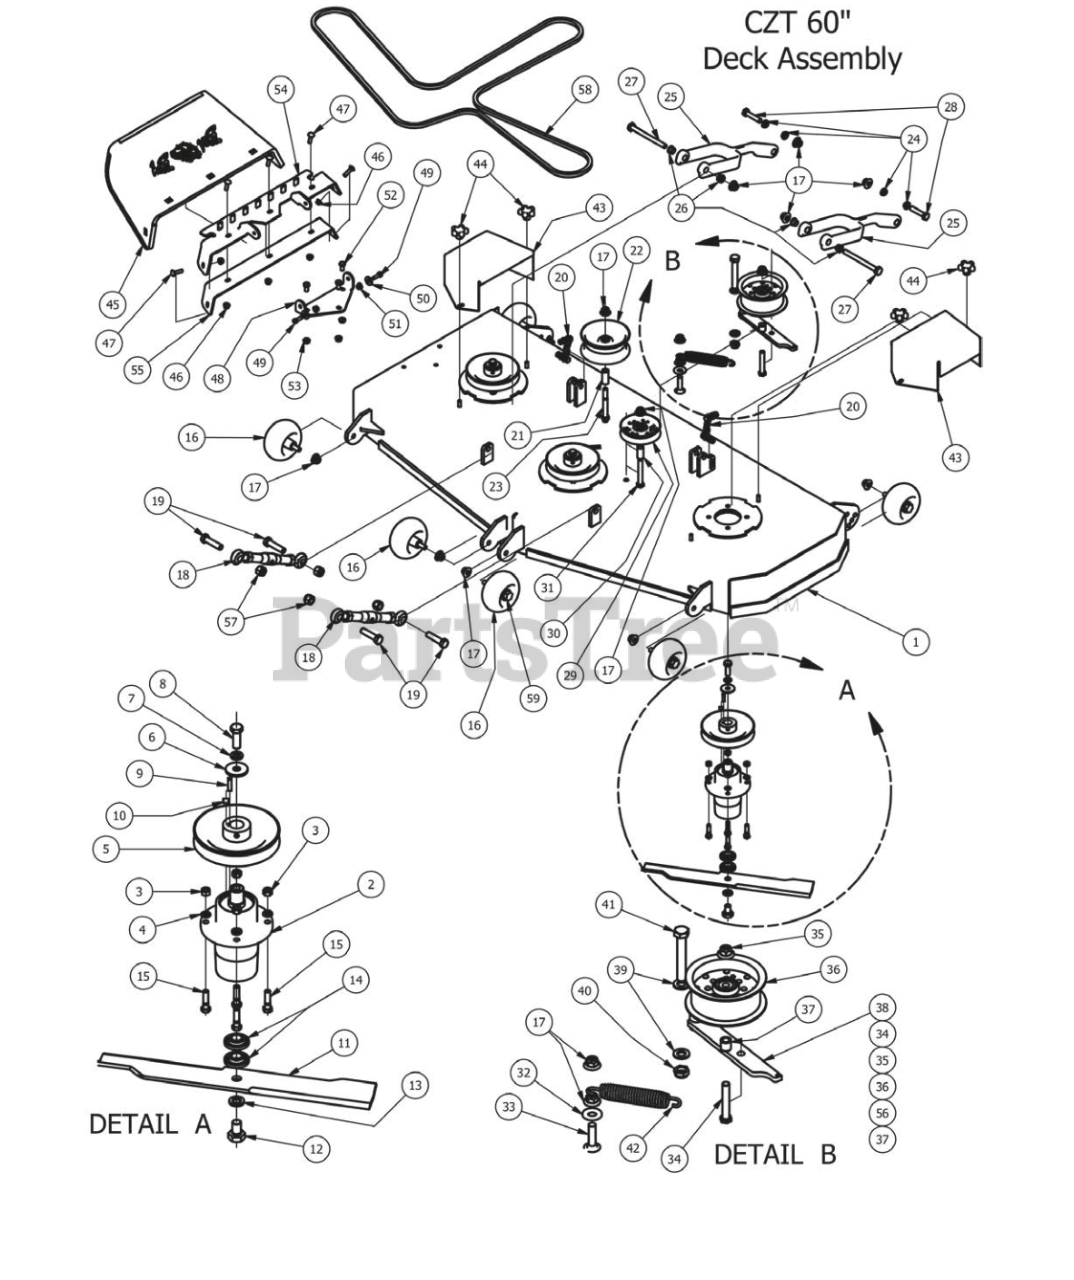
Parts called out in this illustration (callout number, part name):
1	2013 60" CZT Deck
2	Short Shaft Spindle
3	3/8" Hex Nut
4	3/8" Lock Washer
5	6 1/4" Drive Pulley
6	1/2 Belleville Washer
7	1/2" Lock Washer
8	1/2"-20 x 1 1/2 - Grade 5 Fine Thread Bolt
9	1/4" x 1" Key
10	5/16 Set Screw
11	60 Inch Fusion Blade
12	5/8" x 1 1/2" Grade 8 Bolt
13	5/8" Lock Washer
14	Spindle Bearing
15	3/8" x 1 1/2" Hex Bolt
16	Deck Wheel
17	1/2-13 Nylon Flange Nut-Orange
18	Turnbuckle (Top Link)
19	5/8" x 2 1/2" Hex Bolt
20	Chain assembly
21	1 3/4" Pulley Spacer
22	5 3/4" Deck Idler Pulley
23	1/2" x 4" Bolt (Grade 8)
24	Flange for Lower Deck Arm
25	Deck Arm Assembly
26	Flange Bushing For Deck Arm upper
27	1/2" x 5 1/2" Bolt
28	1/2-13X 2-1/4 GR Hex Bolts
29	4-3/4 Idler Pulley
30	.502 ID X.75 OD X 1.500 Leng
31	1/2 x 3 1/2 Flange Bolt Grade 8
32	1/2" Flat Washer
33	1/2 x 2" Carriage Bolt
34	1/2-13 x GR 5 Hex Bolt Zinc
35	1/2-13 Nylon Flange Nut-Orange
36	5 3/4 flat idler-32f1-92-008
37	3/4 OD x 1/2 ID x 3\4 Length
38	Deck Idler Bracket
39	.635 ID Plastic Washer
40	5/8" Nylock (1/2 Jam)
41	5/8" x 4" Hex Bolt
42	2009 Deck/Pump Idler Spring
43	Pulley Cover
44	5/16" Knob
45	Rubber Discharge Chute
46	5/16" Nylon Flange Nut
47	5/16" x 1 1/4" Carriage Bolt
48	Discharge Chute Hanger (deck mounted)
49	5/16" x 1" Bolt
50	.360 ID Plastic Washer
51	5/16" Nylon Flange Nut
52	3/8" x 3/4" Hex Bolt
53	3/8" Flange Nut
54	60" Upper Hanger Plate
55	60" Lower Hanger
56	Deck Idler Assembly (Components 34,35,36,37,38)
57	5/8 Std NC Nylock Nut
58	60" ZT Deck Belt
59	Deck Wheel Bolt
